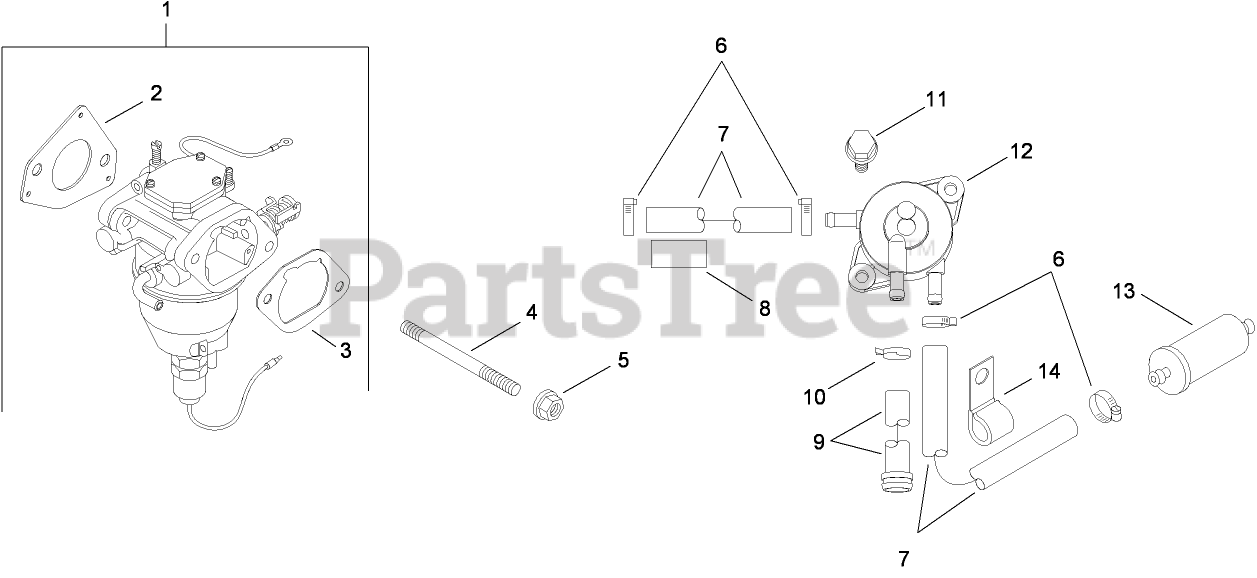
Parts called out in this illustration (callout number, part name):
1	CARBURETOR KIT W/GASKETS (INCLUDES 2-3)
2	GASKET-CARBURETOR
3	GASKET-BASE, AIR CLEANER
4	STUD (M6X1.0X106)
5	NUT-FLANGE (M6X1.0)
6	CLAMP-HOSE, SPRING (1/2)
7	LINE-FUEL (24-CUT TO LENGTH)
8	SLEEVE-ABRASION, ANTI
9	HOSE-FUEL PUMP W/CLAMP (INCLUDES 10)
10	CLAMP-HOSE
11	SCREW-TAP (M6X1.7X18)
12	PUMP-FUEL
14	CLIP-CABLE
15	CHOKE REPAIR/SERVICE KIT
16	GASKET REPAIR/SERVICE KIT
17	FLOAT REPAIR KIT
18	SOLENOID VALVE REPAIR KIT
19	REPAIR OVERHAUL KIT
